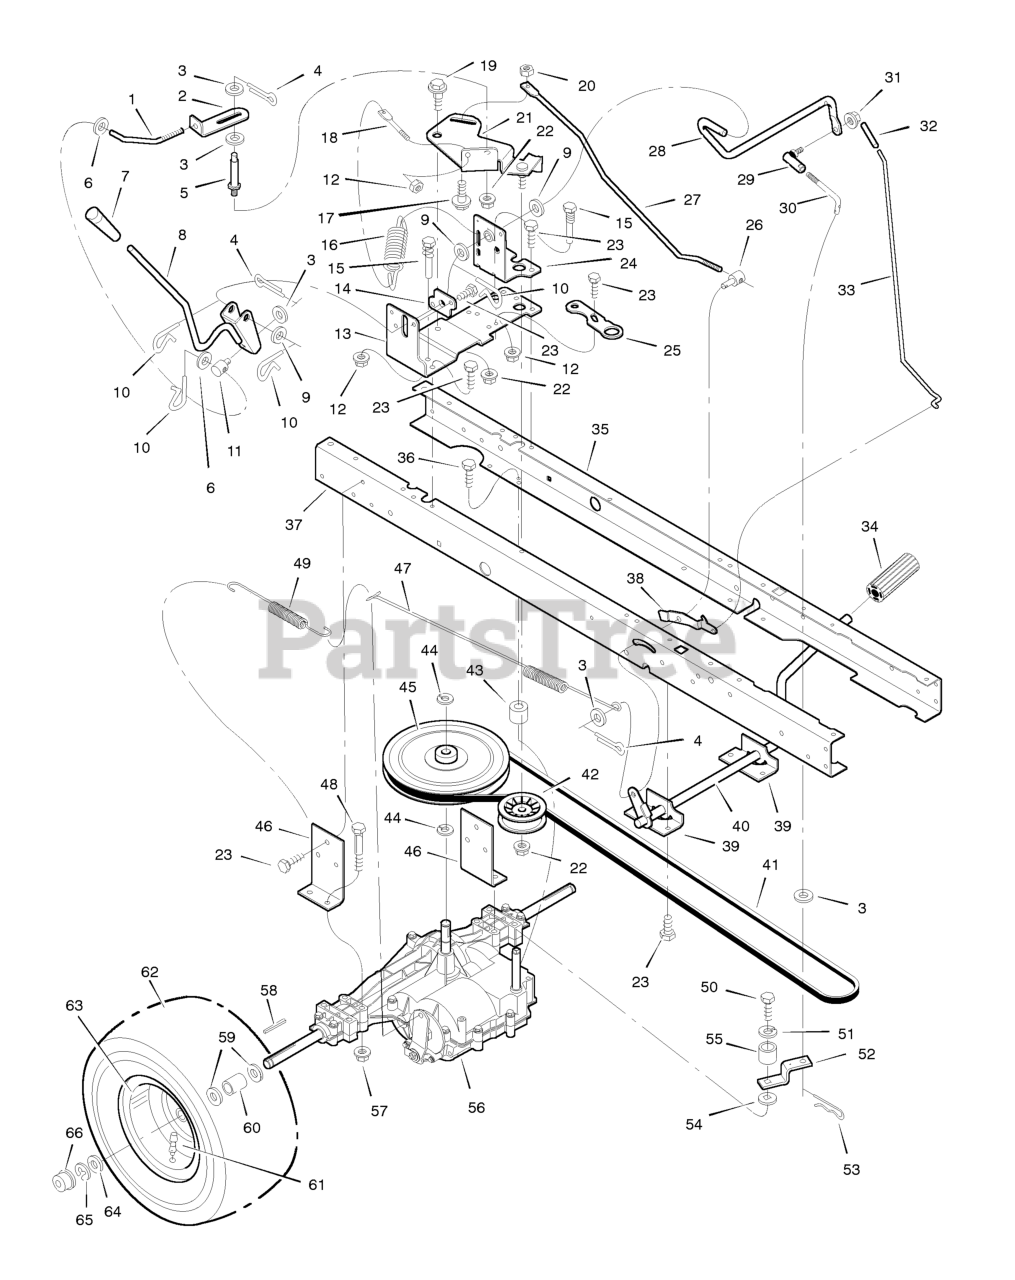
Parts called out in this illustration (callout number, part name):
1	Rod, Adjuster
2	Link, Clutch
3	Washer
4	Pin, Cotter
5	Spacer, Stud
6	Washer
8	Lever, Shift
9	Washer
10	Pin, Hair
12	Nut, Flange
13	Bracket, Shifter
14	Plate, Pivot
15	Guide, Belt
16	Spring, Extension
17	Bolt, Shoulder
18	Stud, Spring
19	Bolt, Shoulder
20	Locknut
21	Arm Assembly, Idler
22	Locknut
24	Bracket, Shift
25	Plate, Shift
26	Nut, Adjuster
27	Rod, Clutch
28	Rod, Shift
29	Joint, Ball
30	Link, Shift
31	Locknut
33	Rod, Parking Brake
34	Pedal
35	Frame, Left
37	Frame, Right
38	Latch, Parking Brake
39	Bracket, Pedal
40	Lever, Clutch/Brake
42	Pulley, Idler
44	Ring, Snap
45	Pulley, Drive
46	Bracket, Transaxle
47	Spring, Extension
48	Bolt
49	Spring, Extension
51	Lockwasher
52	Yoke, Shift
53	Pin, Hair
55	Spacer
56	Transaxle **
57	Nut, Flange
58	Key, Square
61	Stem, Valve
62	Tire *
63	Wheel & Tire Assembly
66	Cap, Hub
